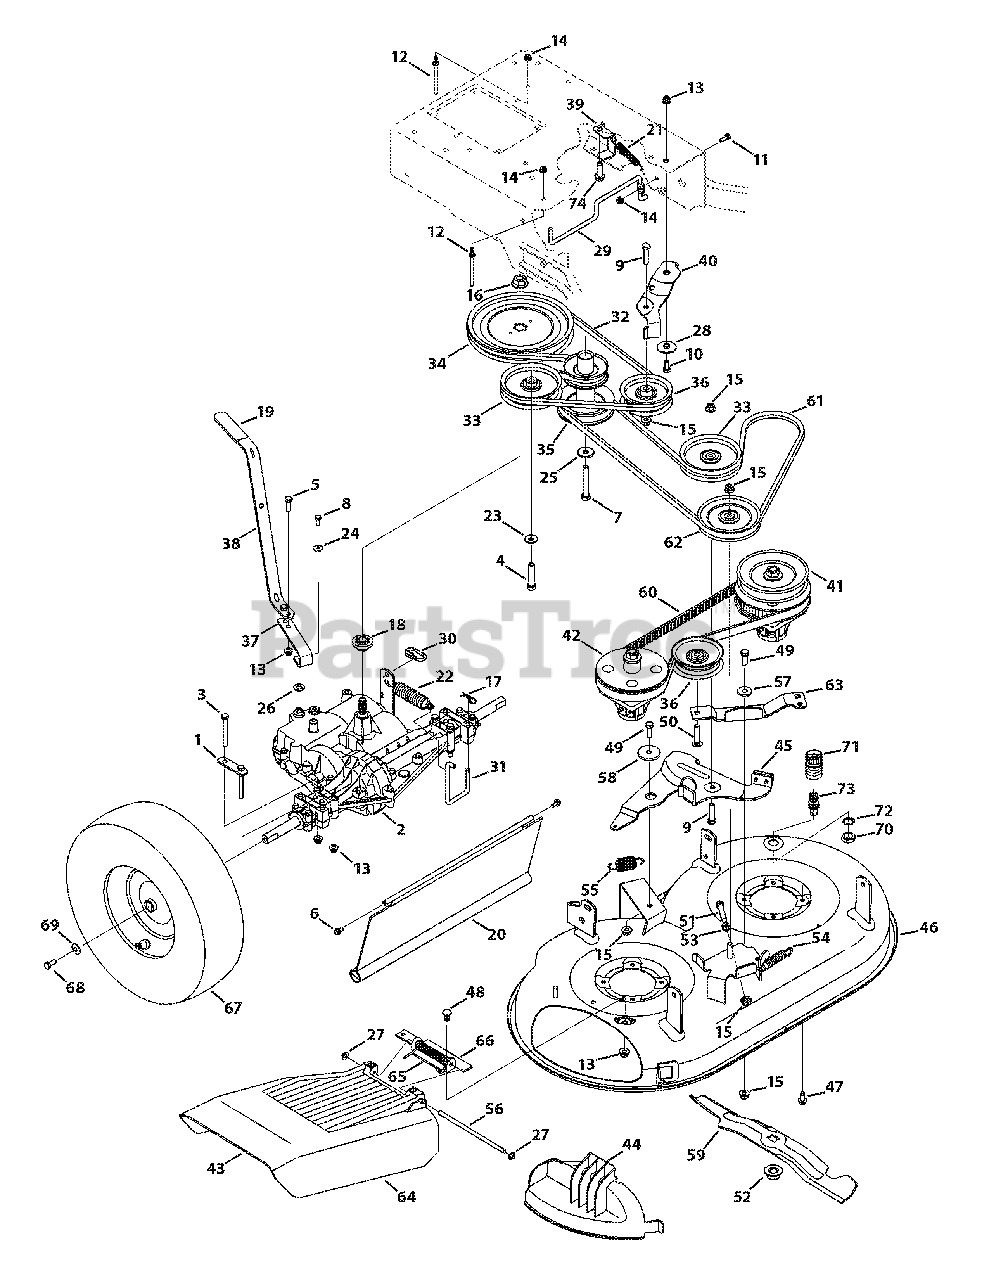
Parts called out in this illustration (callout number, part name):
1	Transaxle Mounting Bracket
2	4 Speed Drive Assembly
3	Hex Head Cap Screw, 5/16-18 x 2.75
4	Hex Head Cap Screw, 3/8-16 x 1.75
5	Hex Head Cap Screw, 5/16-18 x 1.00
6	Screw, 1/4-15 x 0.50
7	Hex Head Cap Screw, 7/16-20 x 2.75
8	Hex Head Cap Screw, 1/4-28 x .625
9	Hex Head Cap Screw, 3/8-16 x 1.50
10	Hex Head Cap Screw, 5/16-18 x .75
11	Hex Head Cap Screw, 1/4-20 x .75
12	Belt Keeper, .25 DIA X 3.0
13	Flangelock Nut, 5/16-18
14	Flangelock Nut, 1/4-20
15	Flangelock Nut, 3/8-16
16	Flange Nut, 9/16-18
17	Click Pin, .092 x 1.64 LG
18	Spline Pulley Hub, 5/8
19	Grip, Black
20	Trailshield, 8.35 x 19.17
21	Extension Spring, Wheel Drive
22	Extension Spring, Brake
23	Washer, Spring, .401 x .870 x .063
24	Washer, Bell, .265 x .75 x .062
25	Washer, Flat, .450 x 1.250 x .164
26	Washer, Flat, .39 x .87 x .06
27	Push Cap
28	Spacer, Shoulder, .5000 x .1475
29	Belt Keeper Rod
30	Coupling Link, .188
31	Brake Spring Mounting Rod
32	V Belt. 4L 64.2
33	Idler Pulley, 4.25 DIA
34	Flat Sheave, DIA 7.75
35	Engine Pulley, 3.20 x 4.35 DIA
36	Idler Pulley, 3.50 DIA
37	Lower Shaft Lever
38	Upper Shaft Lever
39	Belt Keeper, .375 x 2.00
40	Wheel Drive Idler Bracket
41	Drive Spindle Assembly
42	Spacer Spindle Assembly
43	Chute Deflector Assembly
44	Mulch Cover
45	Idler Arm Assembly
46	Deck Assembly
47	Screw, 5/16-18 x .750
48	Bolt, Carriage, 5/16-18 x .750
49	Hex Head Cap Screw, 3/8-16 x 1.00
50	Screw, Carriage, 3/8-16 x 1.75
51	Hex Head Cap Screw, 3/8-16 x 2.00
52	Flange Nut, 5/8-18
53	Hex Nut, 3/8-16
54	Extension Spring, Timing Belt
55	Extension Spring, Deck Brake
56	Deflector Pin
57	Shoulder Spacer, .625 ID x .169
58	Shoulder Spacer, .8840 x .190
59	2 in 1 Blade
60	Timing Belt, .315 x .787
61	Aramid V Belt, 72.2
62	Idler Pulley, V-Type, 5.0 DIA
63	Timing Idler Bracket
64	Chute Deflector
65	Deflector Torsion Spring
66	Deflector Hinge Bracket
67	Wheel, 16 x 4 x 8
68	Hex Screw, 5/16-24 x .750
69	Washer, Bell, .340 x .872 x .060
70	Nut, Hex, M16-1.5
71	Water Nozzle Adaptor
72	Washer, Lock, 5/8
73	Deck Water Nozzle
74	Screw, 3/8-16 x 1.250
